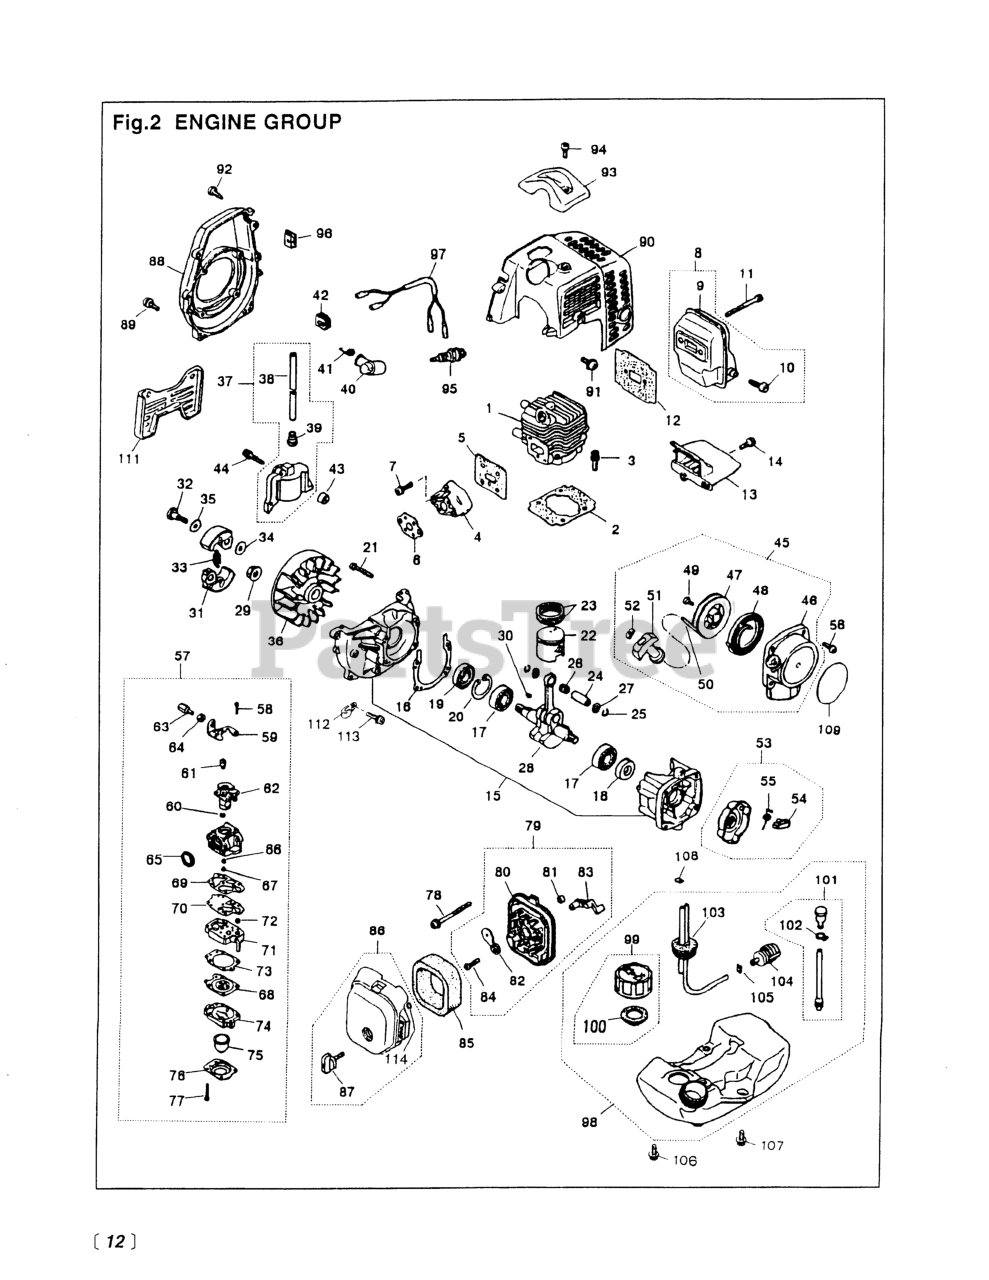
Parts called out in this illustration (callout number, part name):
1	CYLINDER
3	BOLT, M5 X 22
4	INSULATOR (USE -13163)
7	SCREW, M5X20 (RPLS.1400-75510)
9	MUFFLER ASSY (USE 5913-15100)
10	ARRESTER (RPLS 5850-15140)
11	BOLT, M5 x 50
12	GASKET, MUFFLER
14	SCREW, M4 X 16
15	CRANKCASE
17	BEARING
18	SEAL, OIL (RPLS 1100-21210)
19	SEAL, OIL (RPLS 1140-21220)
20	RING, SNAP, M28 x 1.2
21	BOLT, M5 X 30
22	PISTON
23	RING, PISTON
24	PIN, PISTON
25	RING, SNAP (RPLS 1101-41320)
27	WASHER
28	CRANKSHAFT (RPLS 1850-42000)
30	KEY
31	SHOE (RPLS 1100-51114)
32	BOLT
33	SPRING, CLUTCH (RPLS-51220)
34	WASHER, FLAT (USE 182303)
38	CORD
39	CAP
41	SPRING
42	GROMMET
43	SPACER (RPLS -71260)
44	BOLT
45	RECOIL ASSEMBLY
46	CASE
47	REEL
48	SPRING, SPIRAL
49	SCREW (RPLS -75150)
51	KNOB
52	PLATE, STOPPER
53	PULLEY ASSY (RPLS -75210)
54	RATCHET (RPLS 1850-75220)
55	SPRING, RETURN
56	SCREW, M4 X 16
57	CARBURETOR (WYJ-117)
58	SCREW
60	RING
61	SWIVEL
62	VALVE ASSY
63	SCREW, CABLE ADJUSTER
64	NUT, CABLE ADJUSTER
65	RING, PACKING
66	RING, O
68	DIAPHRAGM (USE 4810-81260)
69	GASKET, PUMP
70	DIAPHRAGM
71	BODY, PUMP
73	GASKET, DIAPHRAGM
74	BODY, PURGE
75	PUMP, PRIMING
76	COVER, PUMP
77	SCREW
78	SCREW, M5 X 55
80	BODY
81	SLEEVE
82	PLATE, CHOKE (RPLS-82130)
83	LEVER, CHOKE
84	SCREW (REPLACES 50030272)
85	ELEMENT
88	COVER, FAN (RPLS-31110)
89	SCREW, M5X20 (RPLS.1400-75510)
91	SCREW, M5 x 12
92	SCREW, HOUSING
93	GUARD, PLUG
94	SCREW,M5 X 14 (RPLS 1400-15510
97	CORD COMP (RPLS -73200)
99	CAP (RPLS -85200)
100	PACKING
102	CLIP
103	PIPE COMPLETE
104	FILTER (RPLS 1850-85300)
105	CLIP (REPLACES 2841-31280)
106	SCREW
107	SCREW W/ WASHER
108	CLIP
111	STAND
112	CLAMP
113	SCREW,M5 X 14 (RPLS 1400-15510
114	RING
